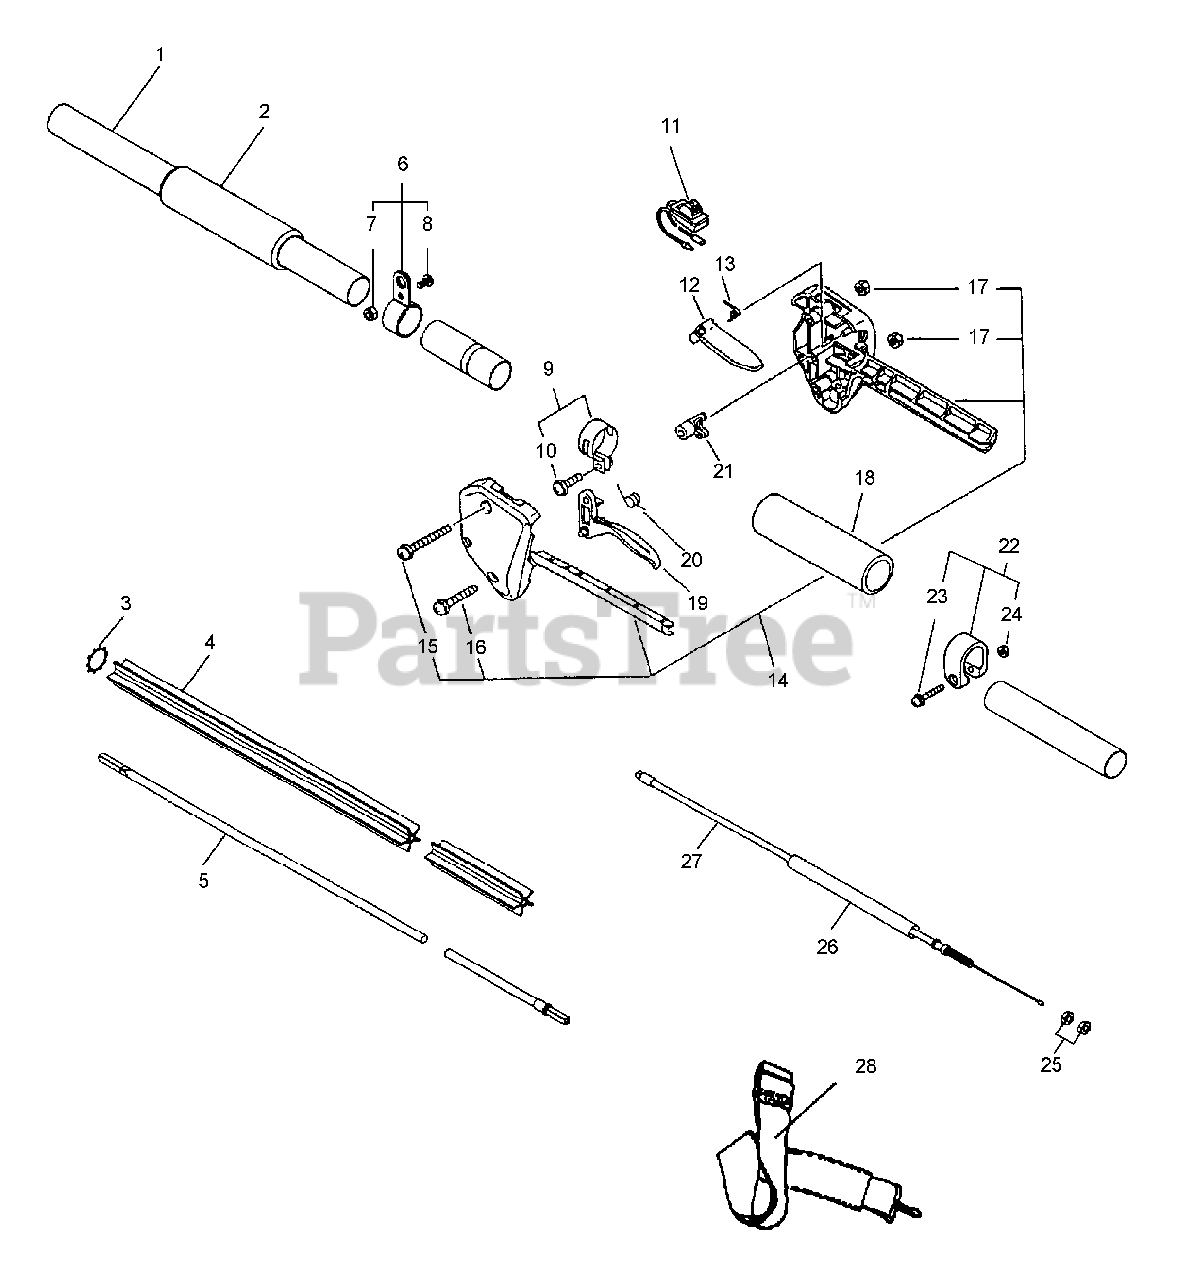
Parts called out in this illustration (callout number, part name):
1	MAIN PIPE ASSY
2	GRIP, HANDLE
4	LINER - FLEXIBLE
5	DRIVESHAFT - FLEXIBLE
6	HANGER KIT
7	NUT, LOCK 10-24 UNC
8	SCREW
9	CLAMP KIT
10	SCREW 5×14
11	SWITCH ASSY, ON-OFF
12	LEVER, THROTTLE LOCKOUT
13	SPRING, TORSION
14	HANDLE KIT, CONTROL
15	SCREW 5×35
16	SCREW 5×25
17	NUT M5
18	GRIP, HANDLE
19	TRIGGER, THROTTLE
20	SPRING, TORSION
21	LOCKOUT, THROTTLE
22	CLAMP KIT
23	SCREW 5×28
24	NUT M5
27	CABLE, THROTTLE
28	STRAP ASSY, SHOULDER
